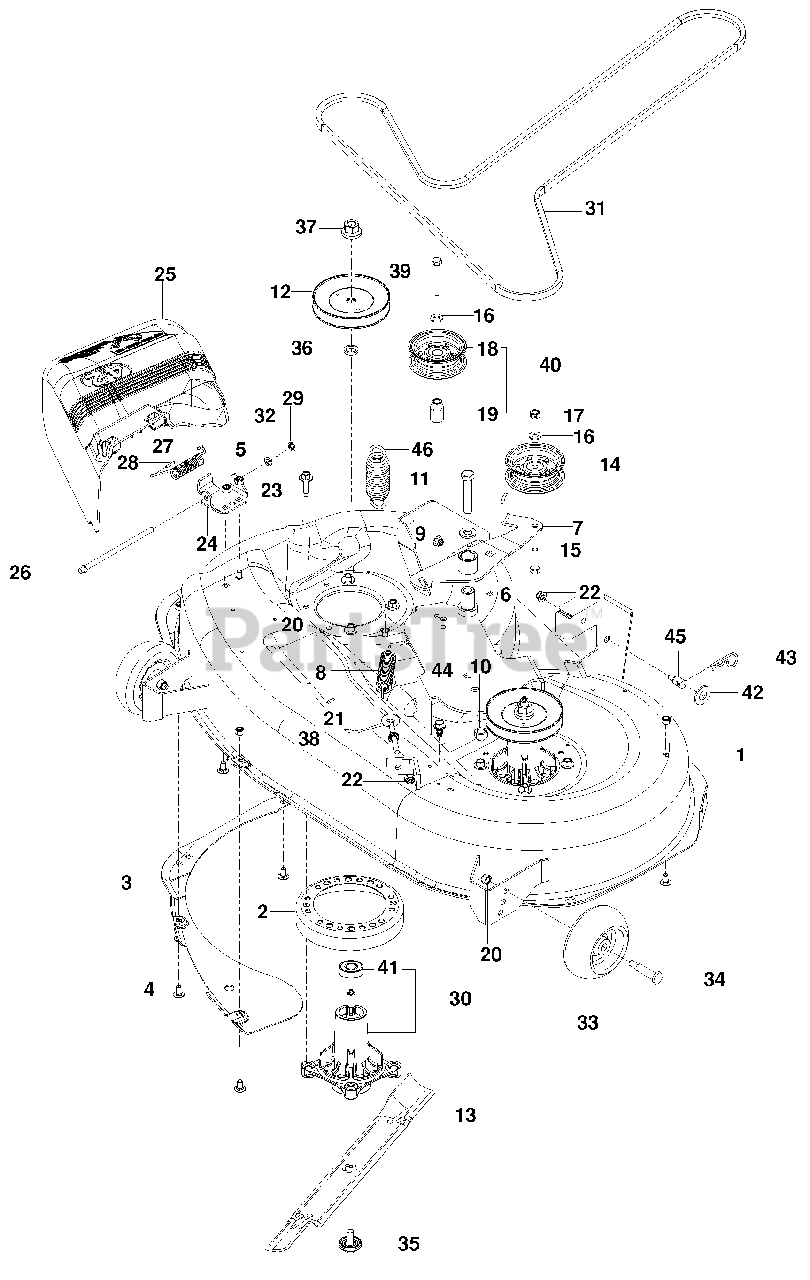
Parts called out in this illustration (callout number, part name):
1	DECK w/ SAFETY DECALS
2	STRIPPER, ROUND
3	BAFFLE VORTEX
4	RHSNB 5/16-18 x 5/8
5	NUT 5/16-18 HEX NYLOC
6	SPINDLE, IDLER
7	ARM, DECK IDLER
8	SPRING, TRACTION
9	WASHER SAE
10	NUT 1/2-13 HEX NYLOC
11	HCS 1/2-13 x 2 3/4
12	PULLEY, MANDREL
13	BLADE 42"
14	PULLEY, DECK IDLER
15	HCS 3/8-16 x 1 1/2
16	WASHER 3/8 SAE FLT
17	NUT 3/8-16 HEX CNTRLK
18	PULLEY, IDLER
19	BEARING, INSERT
20	NUT 3/8-16 HEX NYLOC
21	EYE BOLT 5/16 x 3 1/2
22	NUT 5/16-18 FLANGE NYLOC
23	SCREW 5/16-18 x WSHER HD
24	BRACKET, DEFLECTOR
25	SHIELD, DEFLECTOR
26	ROD, HINGE
27	SPRING, TORSION
28	CAP, SLEEVE
29	PUSHNUT
30	HOUSING, CUTTER
31	BELT, DECK
32	WASHER 11/32 x 5/8 x 16
33	WHEEL, GAUGE
34	SHOULDER BOLT
35	BOLT WASHER ASSY
36	WASHER/SPACER
37	NUT 9/16 TOP CNTRLK
38	NUT 5/16-18 HEX WHIZLK
39	HCS 3/8-16 x 2 1/2
40	PULLEY ASSYBLY, IDLER
42	WASHER 5/8 FLT SAE
43	HAIRPIN #4
44	SCREW 3/8-16 x 3/4, THD CUT
45	STUD w/ ANTI-ROTATE
